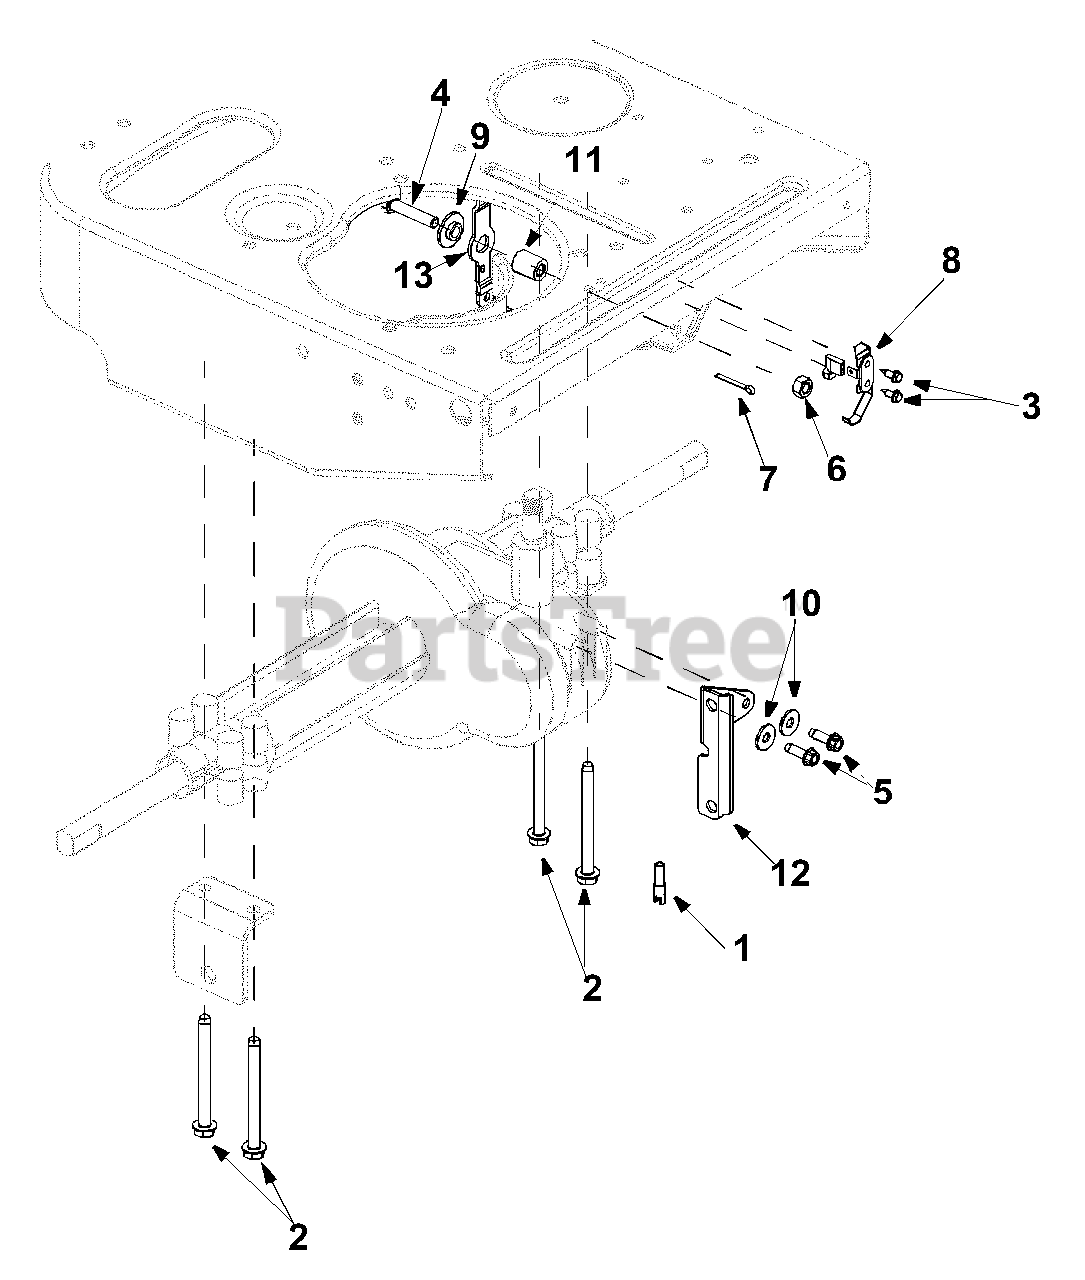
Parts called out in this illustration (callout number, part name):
1	Harness Assembly Adapter
2	Hex TT Screw 5/16-18 x 3.50
3	Hex Washer Head Self-Tap.Scew
4	Hex Screw 5/16-18 x 1.5 Gr. 5
5	Thd. Forming Scr. 1/4-20x .75
6	Hex Lock Nut 5/16-18
7	Cotter Pin
8	Insulator Nut Plate
9	Shoulder Bushing
10	Flat Washer
11	Spacer
